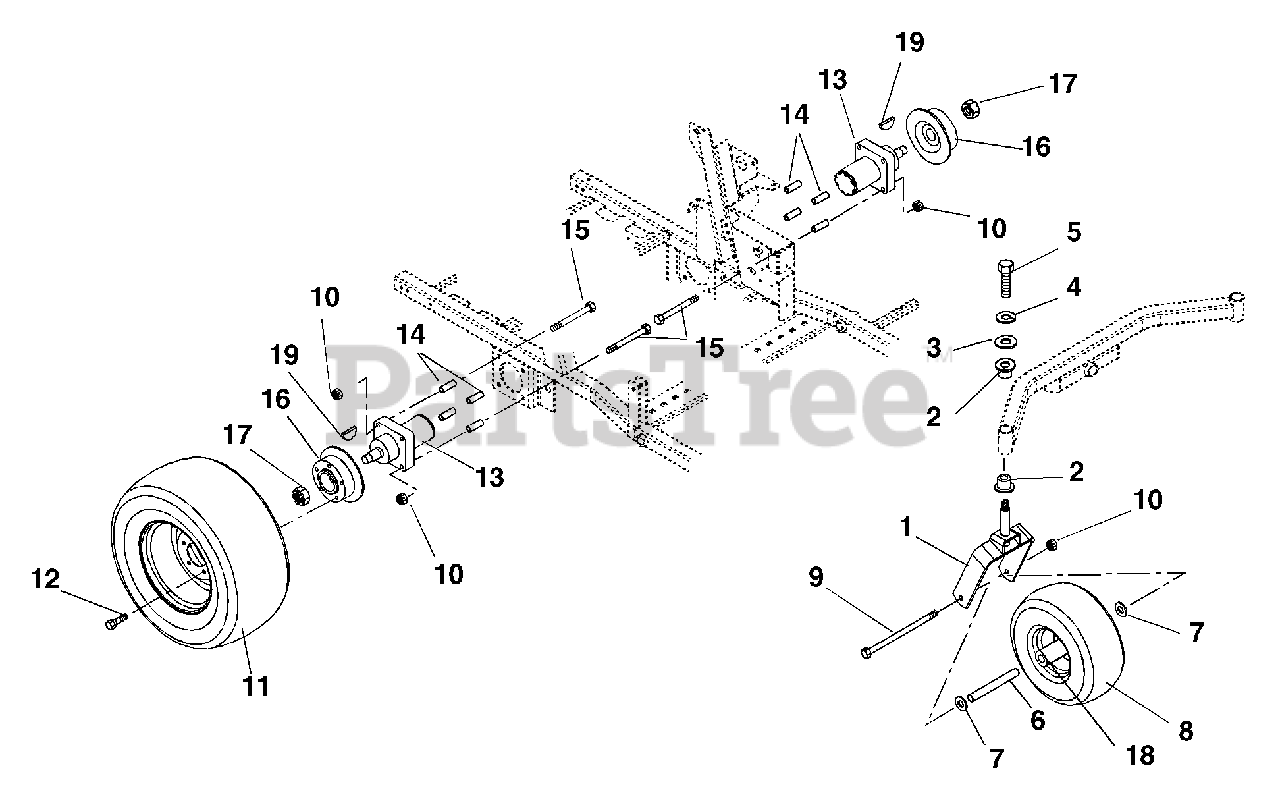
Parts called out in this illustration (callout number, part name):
1	Fork-Front
2	Bushing, Flange 1.020 x 1.385 x .75 x 1.75
3	Washer-Flat-Steel .380 x 1.50 x .125
4	Washer-Locking .38 x .094
5	Bolt-Hex .38-16 x 1.25 Grade 5
6	Spacer-Wheel
7	Washer-Flat-Steel .515 x 1.625 x .250
8	Wheel/Tire Assembly
8	Tire, 15 x 6-6
9	Bolt-Hex .50-13 x 9.00 Grade 5
10	Nut-Locking-Center .50-13
11	Wheel-Tire 23 x 8.50 Multi-Trac
11	Tire 23 x 8.50-12 Multitrac C/S
12	Bolt-Lug .50-20 x 1.62
13	Hydraulic Wheel Motor
14	Bushing-Sleeve .513 x .748 x 1.93
15	Screw-Socket Head .50-13 x 4.50
16	Hub and Disc
17	Nut -Lock Jam Patch
18	Bearing, 25MM I.D. x 52MM O.D. x 15MM
19	Key-Woodruff .31 x 1.00
